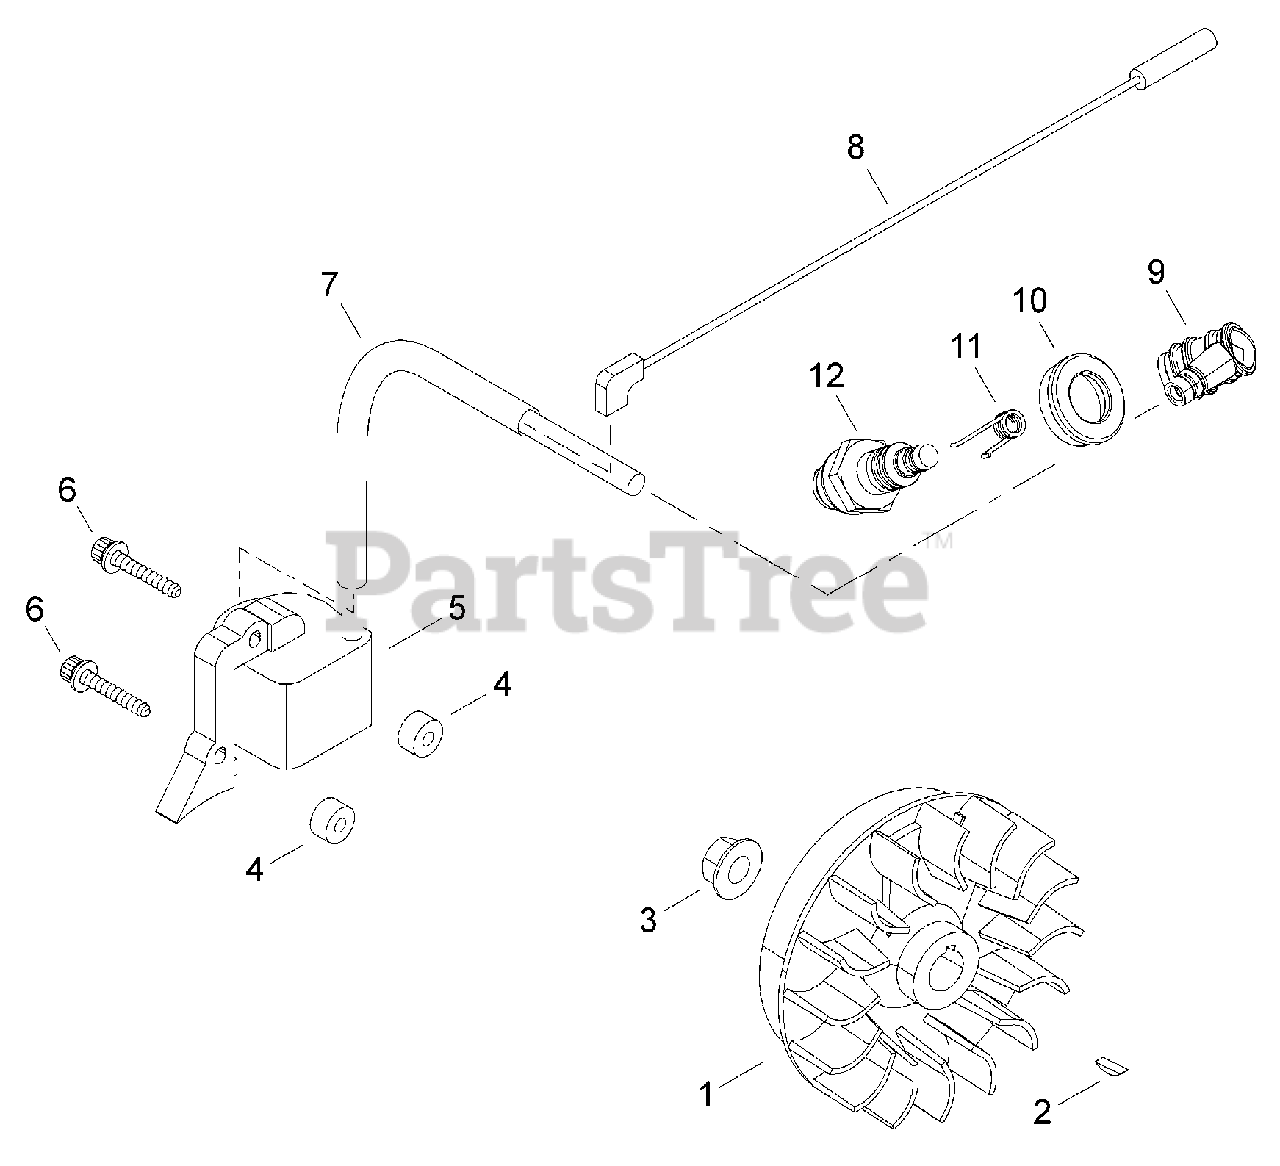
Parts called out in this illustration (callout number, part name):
2	KEY - 3X10
3	NUT - 8
4	INSULATOR
5	COIL, IGNITION
5-1	FLYWHEEL
6	SCREW - 4X20
7	IGNITION COIL SLEEVE
8	LEAD - IGNITION
9	CAP, SPARK PLUG
10	SEAL, DUST
11	TERMINAL, SPARK PLUG CAP
12	SPARK PLUG -- BPMR-6A
